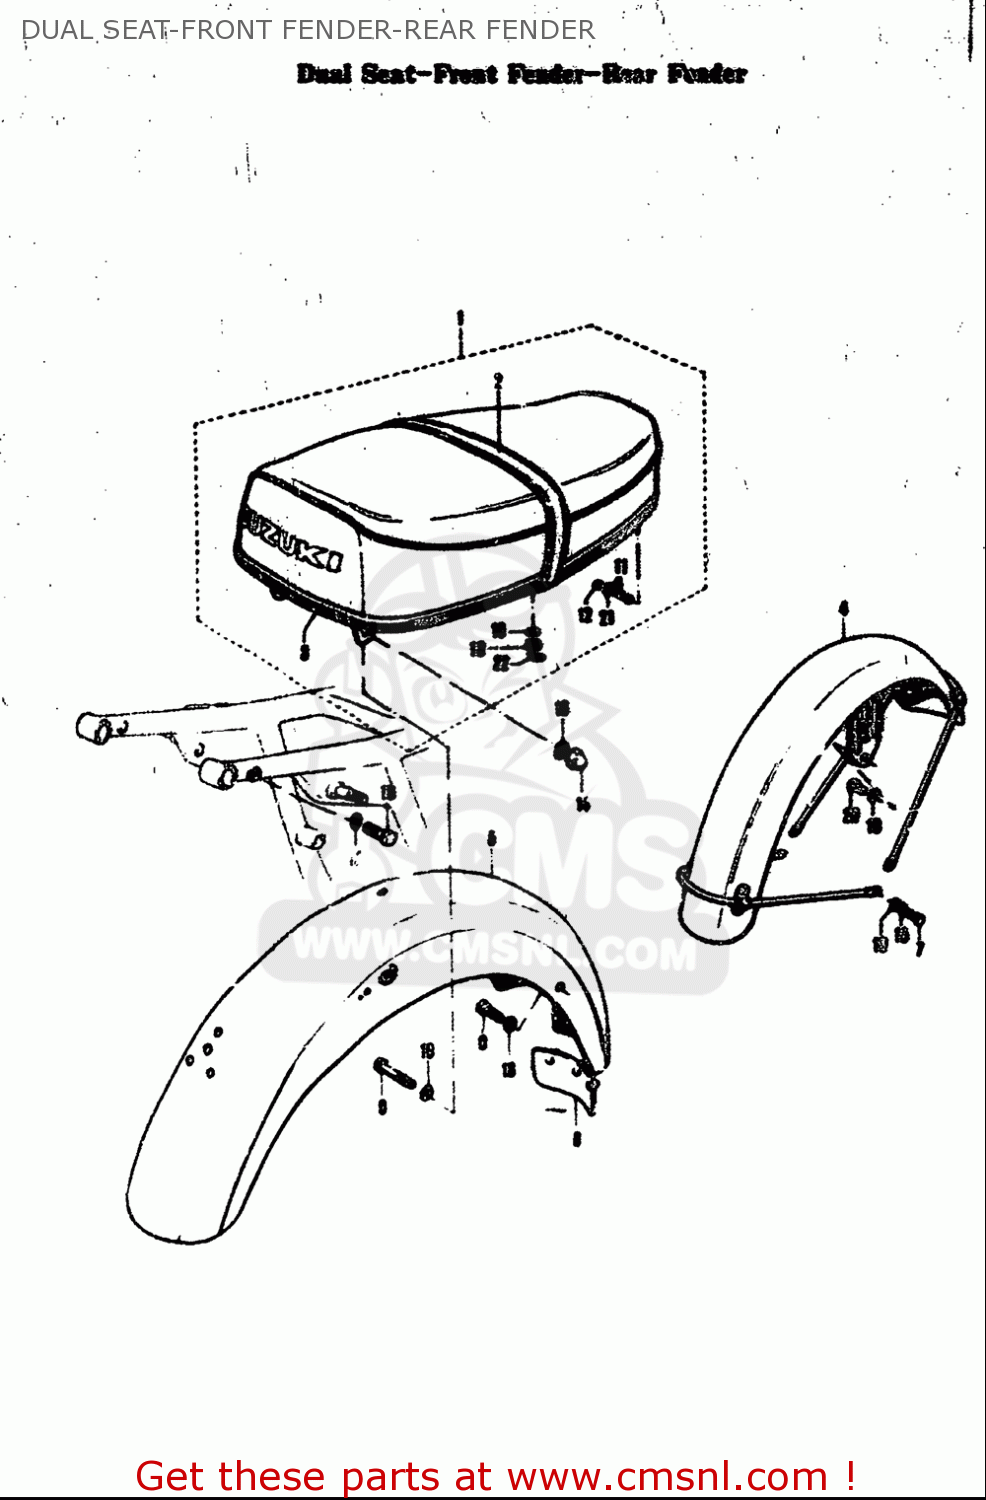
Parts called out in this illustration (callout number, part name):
9	BOLT
10	BOLT
12	NUT
13	NUT
14	NUT
15	WASHER,LOCK
16	WASHER,LOCK
17	WASHER,LOCK
18	WASHER
19	WASHER
20	BOLT
22	CLIP
